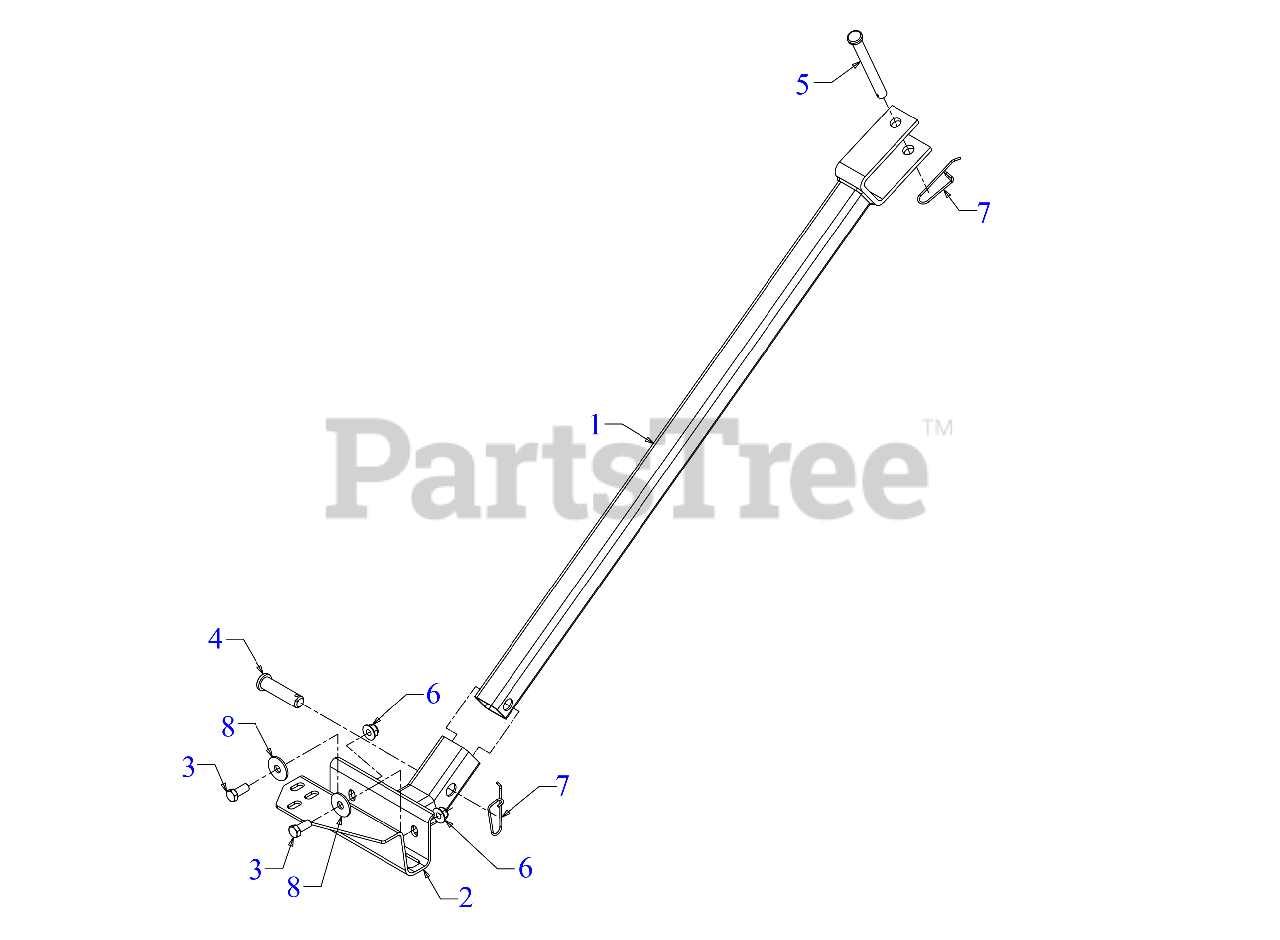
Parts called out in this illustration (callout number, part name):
3	SCREW 3/8-16 x .880 GR5
4	CLEVIS PIN .625 x 2.40
5	CLEVIS PIN
7	SPRING PIN
8	FLAT WASHER
